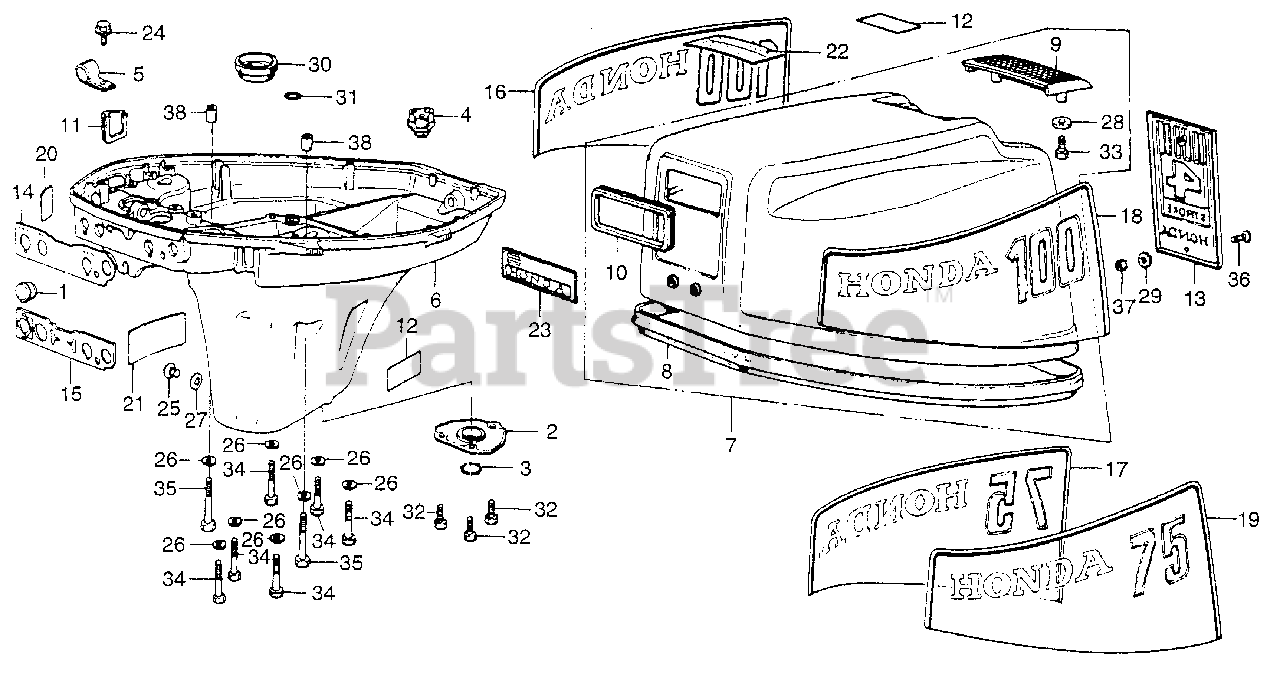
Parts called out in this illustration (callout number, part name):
1	GROMMET C, OIL CASE
2	PLATE, EX.
3	BAND, EX. SEAL
4	MANIFOLD, TUBE
5	CLAMP, WIRE
6	CASE, OIL *B9* (ATLANTIS BLUE)
7	COVER, ENGINE *NH24* (CERAMIC WHITE)
8	SEAL, ENGINE COVER
9	HANDLE, TILT *NH24* (CERAMIC WHITE)
10	SEAL, RECOIL
12	MARK, INSTRUCTION
13	EMBLEM, RR. (NOT AVAILABLE)
14	LABEL, INDICATION (NOT AVAILABLE)
15	LABEL, INDICATION (NOT AVAILABLE)
16	EMBLEM, R. SIDE COVER (NOT AVAILABLE)
18	EMBLEM, L. SIDE COVER
20	MARK, CHANGE
21	LABEL, OIL FILLER POSITION
22	MARK, STARTER CAUTION
24	BOLT, FLANGE (6X12)
25	BOLT, OIL CHECK
26	WASHER, PLAIN (6MM)
27	WASHER, NYLON (8MM)
28	WASHER (6MM)
29	WASHER, LOCK (4MM) (NOT AVAILABLE)
30	SEAL, COUPLING (25X40X22)
31	O-RING (9.8X1.9)
32	BOLT, HEX. (6X12)
33	BOLT, HEX. (6X16)
34	BOLT, HEX. (6X32) (NOT AVAILABLE)
35	BOLT, HEX. (6X40)
36	SCREW, PAN (4X10)
37	NUT, HEX. (4MM)
38	PIN A, DOWEL (8X14)
